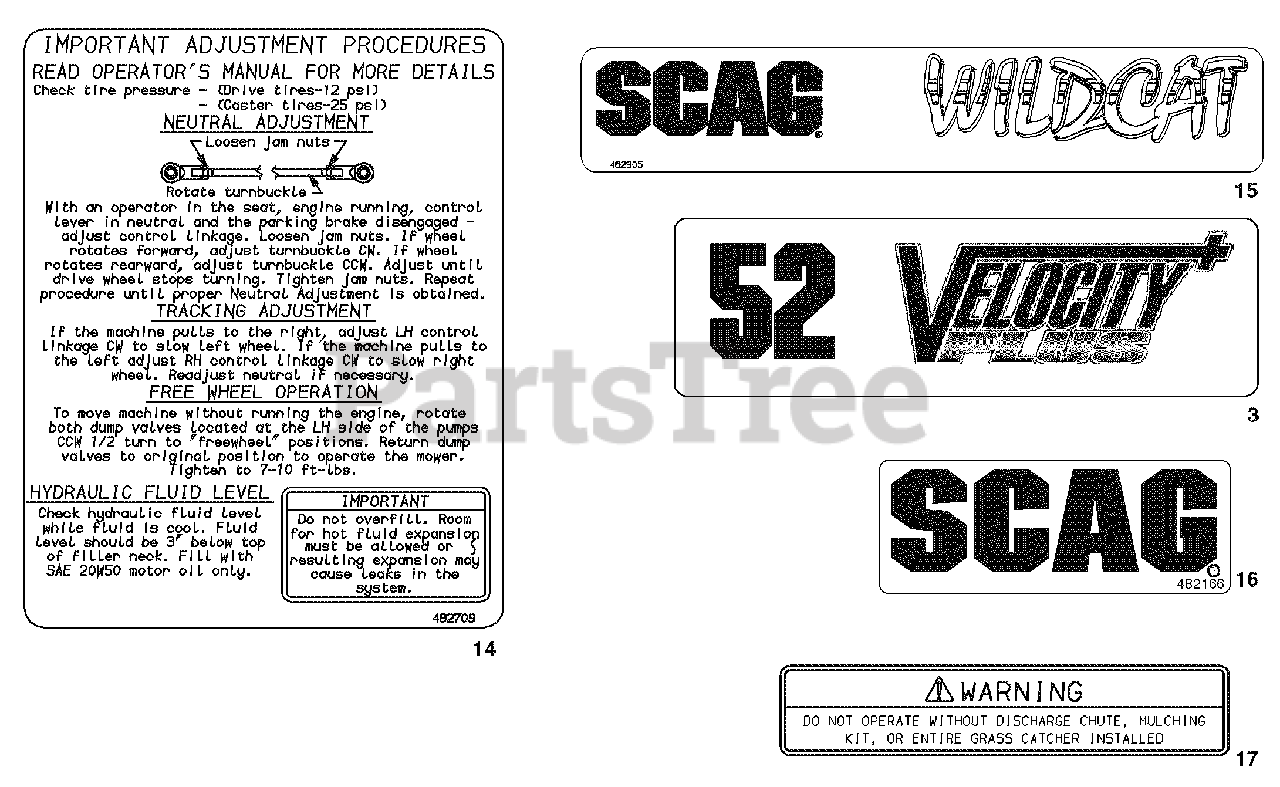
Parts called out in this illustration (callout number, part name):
3	Decal, 61V
14	Decal, Seat Support
15	Decal, Rear Bumper
16	Decal, Front Footplate
17	Decal, Discharge Chute
